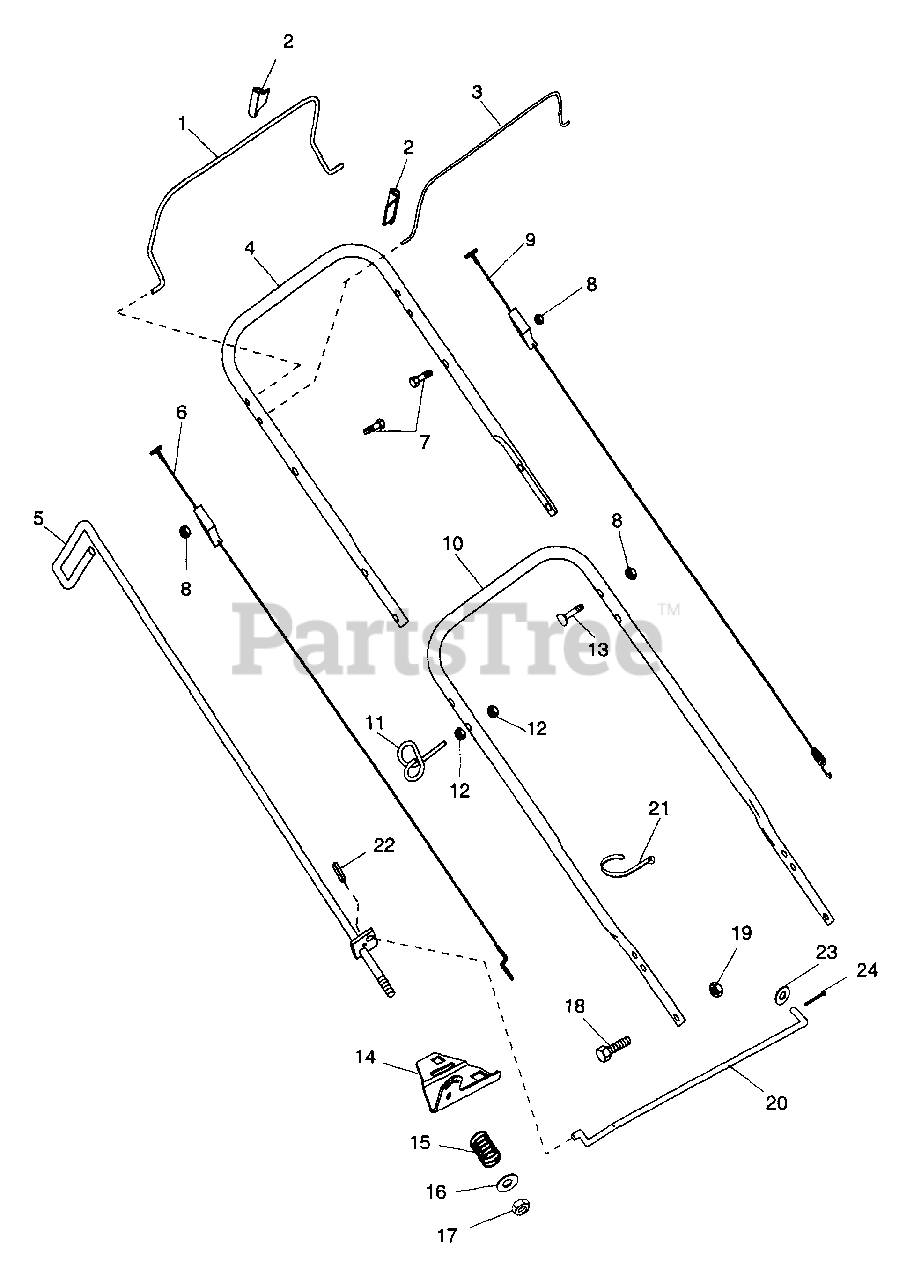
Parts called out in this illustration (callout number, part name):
1	TRACTION BAIL
2	BAIL STOP
4	UPPER HANDLEBAR
5	CRANK ARM WELDMENT
6	CABLE-ENGINE CONTROL
7	BLT-HEX .25-20X1.25 PL GR5
8	NUT-LK TOP .250-20 PL
9	TRACTION CABLE
10	LOWER HANDLEBAR
11	SUPPORT
12	NUT-LK-FLG .250-20 PL
13	BLT-CRVD-HD .25-20X.25 PL
14	SPEED CONTROL BRACKET
15	SG-COMP .65X.56X1.50
16	WSHR-FL-STL.312X.734X.065PL
17	NUT-LK-TOP .312-18 GR C PL
18	BLT-HEX .31-18X.63 PL GR 2
19	NUT-FLG. .312-18 PL
20	LINK ROD
21	CABLE TIE LG 5-1/2
22	PIN-ROLL .125X.63
23	WSHR-FL-STL.281X.62X.065 PL
24	PIN-HAIR INT.06X.25X1.12
